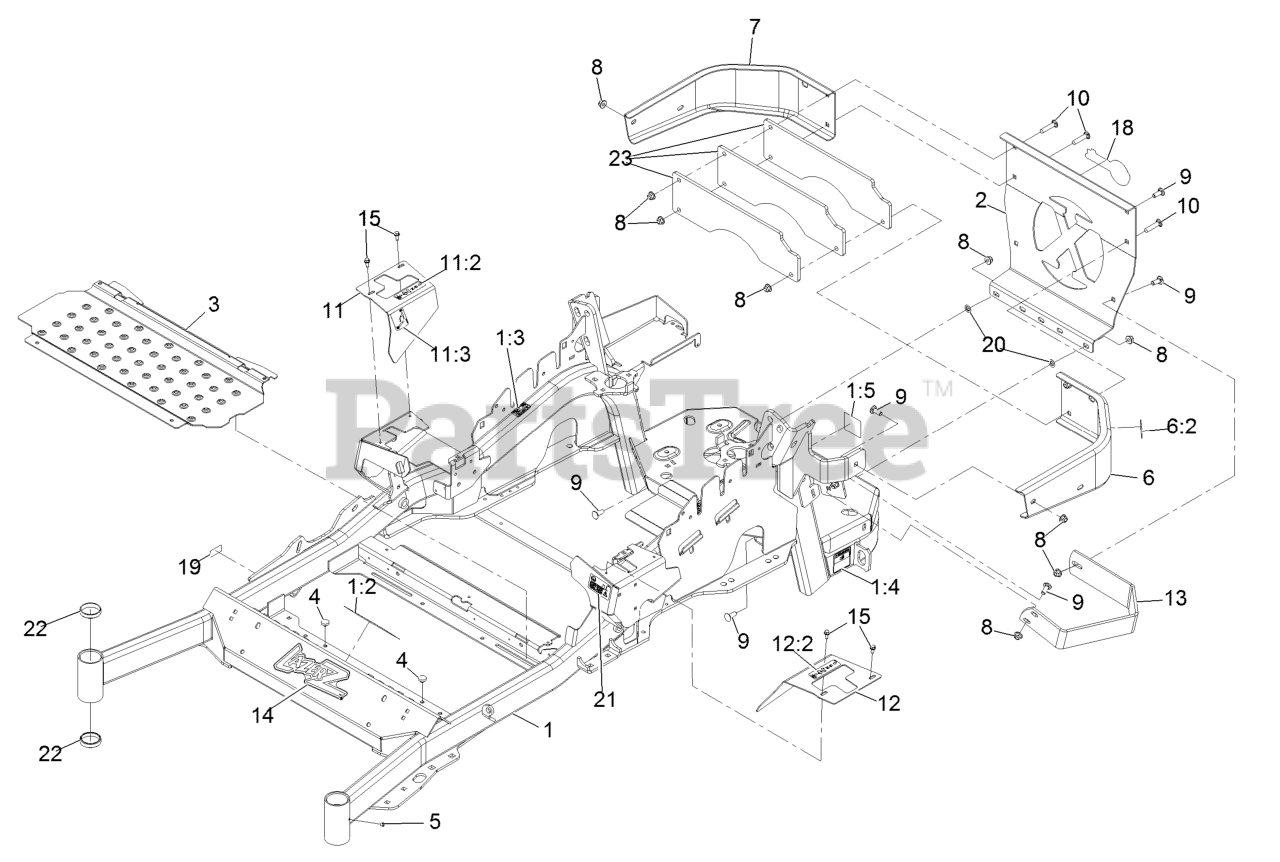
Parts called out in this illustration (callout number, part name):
1	MAINFRAME ASM
1:2	DECAL-WARNING
1:3	DECAL-WARNING, SLOPE
1:4	DECAL-HAZARD, PINCHED FINGER
1:5	DECAL-SPARK ARRESTER
2	PLATE,REAR GUARD
6	LH BUMPER ASM
6:2	DECAL-WARNING
7	BUMPER-RH
8	NUT-HF, NI
9	SCREW-CARR
10	SCREW-CARR
11	RH MOTION CONTROL COVER ASM
11:2	DECAL-CONTROL, MOTION
11:3	DECAL-PARK BRAKE, CE
12	LH MOTION CONTROL COVER ASM
12:2	DECAL-CONTROL, MOTION
13	GUARD-MUFFLER
14	DECAL,LAZER MODEL
15	SCREW-HWH
19	Decal-Patent Ttco.Com
20	NUT-PUSH
21	DECAL-FUEL FILL, CE
22	CUP-BEARING
23	PLATE-WEIGHT, 6 LB
